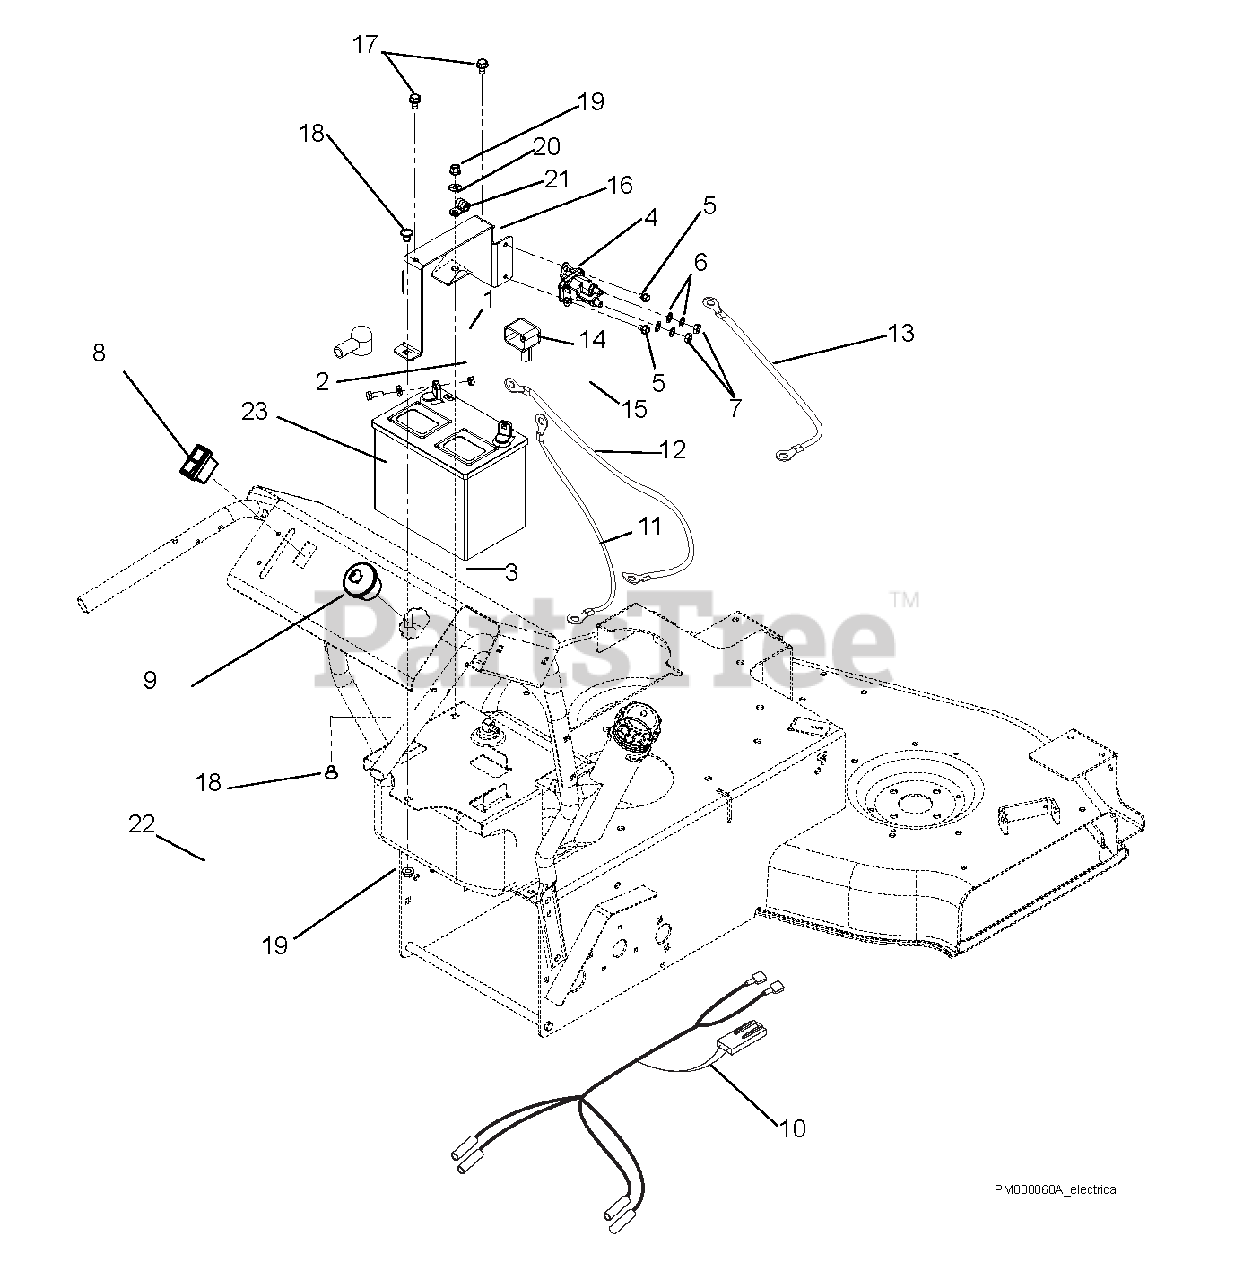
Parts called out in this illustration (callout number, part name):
1	@WSHR-FL-STL.281X.62X.065 YWZC
2	@BLT-HEX .25-20X.75 GR5 YWZC
3	NUT-KEPS .250-20
4	SOLENOID
5	@SCR-TAP .25-20X.37 HWH YWZ TR
6	WSHR-LOCK INT .31 YWZC
7	NUT-JAM .31-24 YWZC
8	SWITCH-ROCKER, MOMENTARY
9	KEYSWITCH-IGNITION 3 POS
9	BRKT, STRIPER MOUNT-RIGHT
10	HARNESS, WAW WIRING
11	CABLE, POS. BAT 18.50"
12	CABLE, NEGATIVE 26" 6 GA.
13	CABLE, POS 6.75" BENT
14	INSULATOR
15	BOOT, EYELET TERMINAL
16	BRKT, BATTERY MOUNT
17	@SCR-TAP .31-18X.50 HWH TR YWZ
18	@BLT-RDHDSQNK .31-18X.50 G5YZ
19	@NUT-LK-TOP-FLG .31-18 YWZC
20	NUT-PUSH .312
21	CLAMP, CUSHIONED STEEL
22	BATTERY MAT WAW 2012
23	BATTERY, 12V 20HR;190CCA GEP
